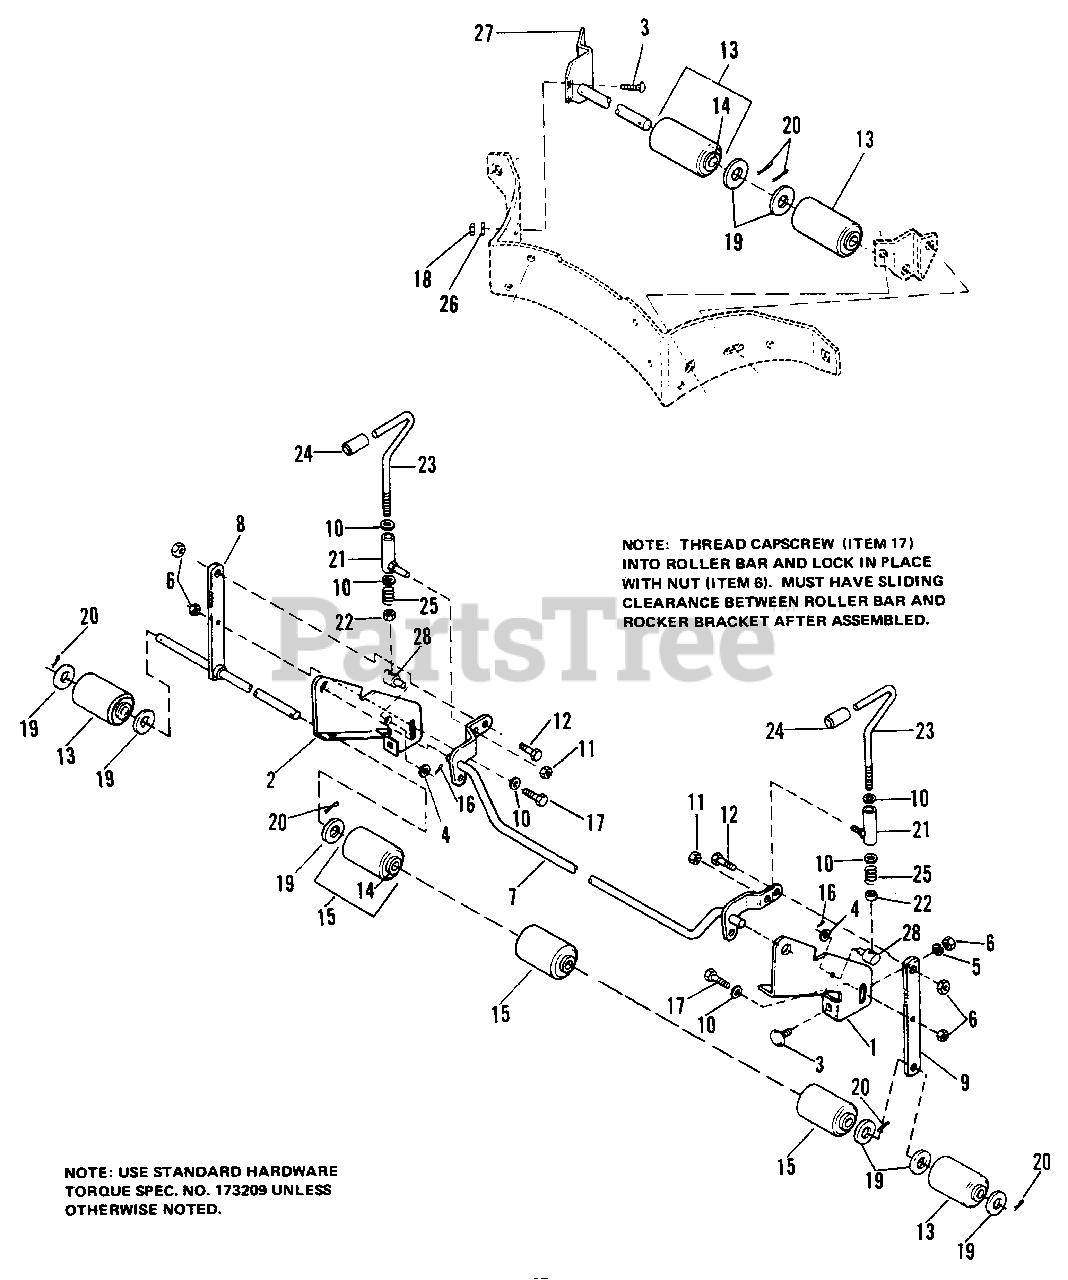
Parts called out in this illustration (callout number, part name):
1	BRACKET, Roller, L.H.
2	BRACKET. Roller, R.H.
3	BOLT, Carriage, 3/8-16 x 3/4
4	WASHER, Plain, 5/16
5	LOCKWASHER, 3/8
6	NUT, Hex, Full, 3/8-16
7	ROCKER ARM ASSY
8	SHAFT ASSY, Roller
9	BAR, Roller
10	WASHER, Plain, 3/8
11	NUT, Hex, Full Lock, 3/8-16
12	CAPSCREW, Hex Hd., 3/8-16 x 1
13	ROLLER ASSY
15	ROLLER ASSY
16	PIN, Cotter. 3/32 x 5/8
17	CAPSCREW, Hex hd., 3/8-16 x 1
18	NUT, Hex, Full, 5/16-18
19	WASHER, Plain, 5/8
20	PIN, Cotter. 3/16 x 1
21	SOCKET ASSY
22	NUT, Hex, Jam, 3/8-16
23	HANDLE, Adjusting
24	GRIP
26	LOCKWASHER, 5/16
27	BRACKET & SHAFT ASSY
